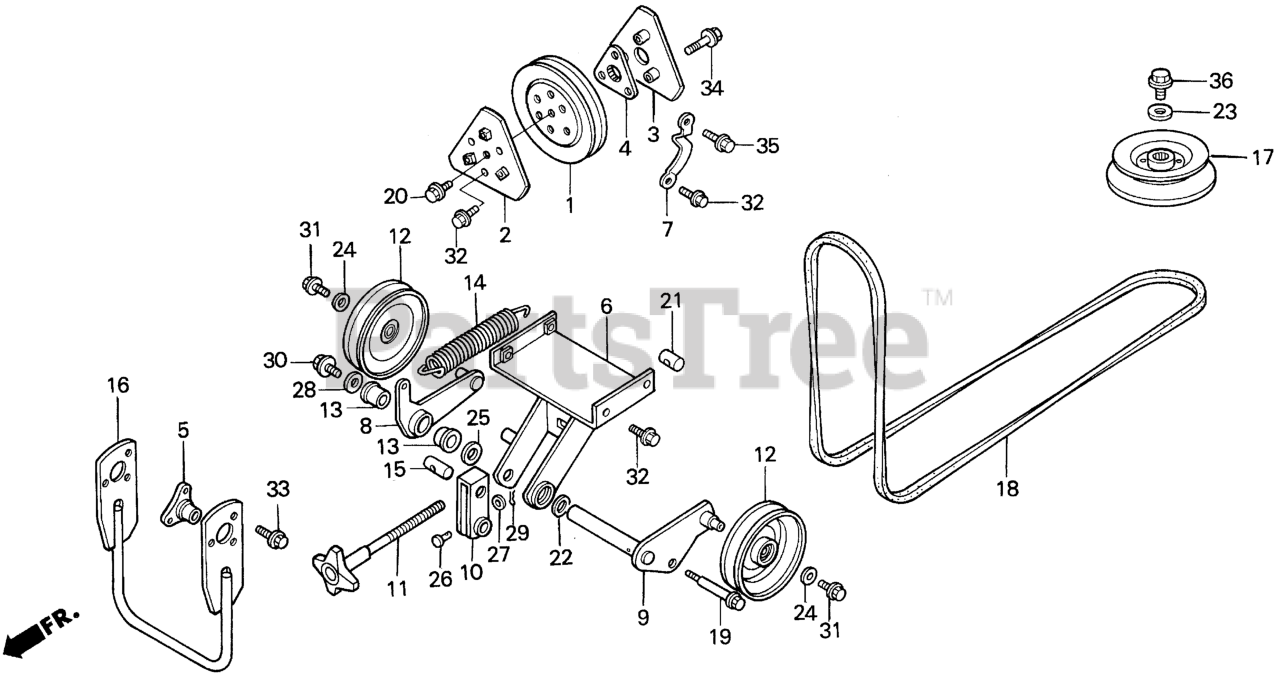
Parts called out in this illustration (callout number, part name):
1	PULLEY, DRIVEN
2	PATCH, PULLEY (A)
3	PATCH B, PULLEY
4	BOSS, DRIVEN PULLEY
5	PIVOT, FR. HITCH
6	BRACKET, TENSIONER
7	STOPPER, V-BELT DRIVEN
8	ARM, TENSIONER (1)
9	ARM, TENSIONER (2)
10	LEVER, TENSIONER
11	KNOB, TENSIONER
12	PULLEY, TENSIONER
13	BUSH (17X23X19)
14	SPRING, TENSIONER
15	PIN, TENSIONER
16	GUARD, TENSIONER
17	PULLEY, DRIVEN
18	V-BELT, DRIVE (LB-89)
19	BOLT, P.T.O. CLUTCH LEVER
20	BOLT, FLANGE (8X20)
21	NUT, TENSIONER
22	COLLAR, TENSIONER BRACKET
23	WASHER (10.5X27)
23	WASHER (10.5X27X4)
24	WASHER, SHIFT DRUM STOPPER
25	WASHER, PLAIN (17.2MM)
26	PIN (6X25)
27	WASHER, PLAIN (6MM)
28	WASHER, PLAIN (8MM)
29	PIN, LOCK (6MM)
30	BOLT, FLANGE (8X14)
31	BOLT, FLANGE (6X12) Use from Engine SN 2086984.
32	BOLT, FLANGE (8X16)
33	BOLT, FLANGE (8X25)
34	BOLT, FLANGE (8X40)
35	BOLT, FLANGE (10X20)
36	BOLT, FLANGE (10X16) (NA USE ALT:95700-10016-08)
